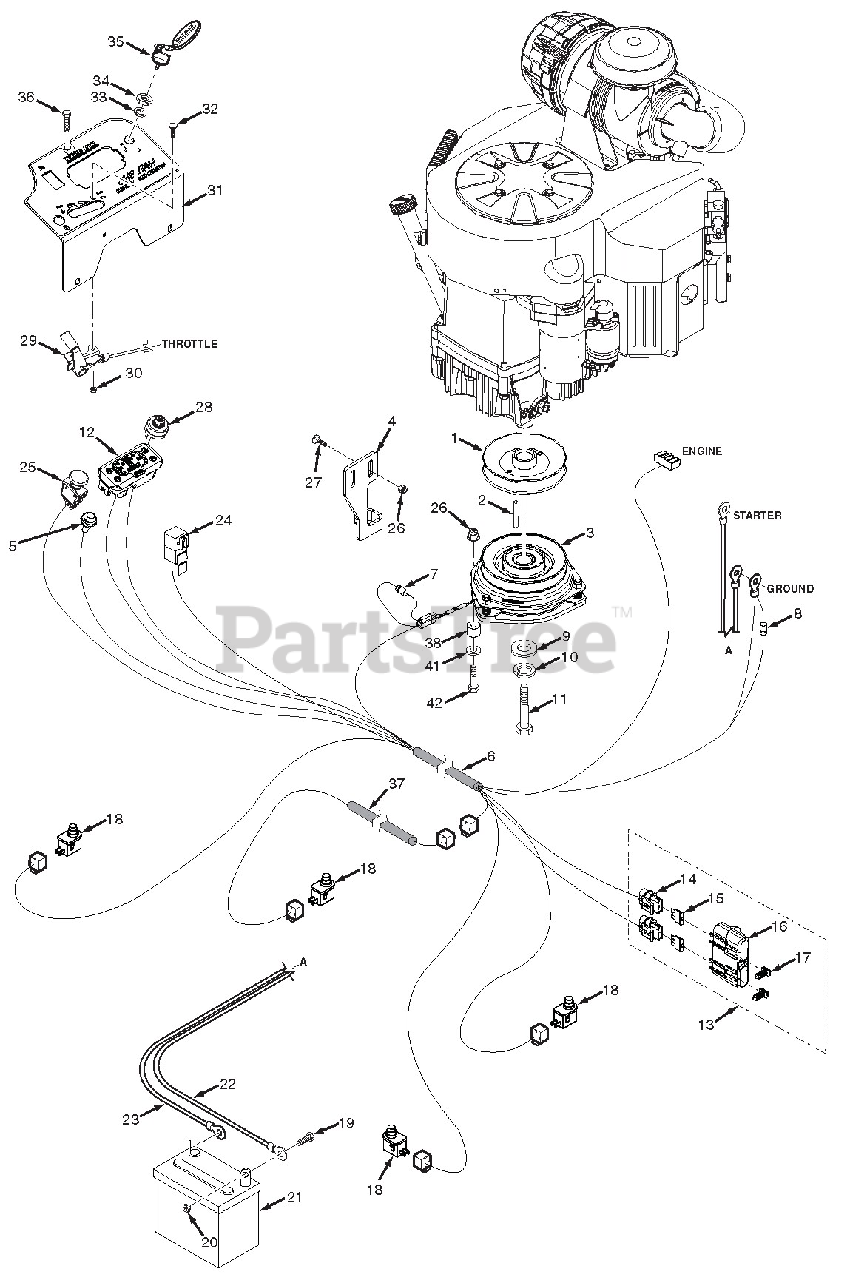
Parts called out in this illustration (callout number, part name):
1	Pulley, 5.80 Dia. - 1.125 Bore
2	Key, 1/4 x 1/4 x 3-1/4"
3	Electric Clutch w/Tag - GT-5 (ECV860, ECV940)
4	Bracket, Anti-Rotation
5	Indicator Light Assembly
6	Wire Harness, SCZ-EFI
7	Diode, 600V - 6A
8	Diode
9	Flatwasher, 7/16-.469 x 1.75 x .25
10	Lockwasher, 7/16" Spring
11	Bolt, Hex Head 7/16-20 x 2-1/4" w/Patch
12	Tiger Eye Cluster Gauge
13	Double Fuse Assembly
14	Fuse Holder
15	Fuse, 20 Amp
16	Cover, Sealed Double
17	Clip, Wire
18	Switch, N.O.
19	Bolt, Hex Head 1/4-20 x 1/2"
20	Nut, 1/4-20
21	Battery
22	Battery Cable, 18" Black
23	Battery Cable, 25" Red
24	Relay
25	Switch, PTO - 10 Amp
26	Nut, FLF HH Elastic Stop 5/16-18
27	Bolt, Carriage 5/16-18 x 1"
28	Keyswitch w/Hardware
29	Control Cable
30	Nut, Elastic Stop #10-24
31	Instrument Panel w/Decal
32	Bolt, Carriage #10-24 x 1/2"
33	Lockwasher, 5/8" Internal
34	Nut, Hex 5/8-32
35	Key Assembly w/Fob
36	Bolt, Hex Head 1/4-20 x 1/2" Serrated Flange
37	Wire Harness, Operator Platform -SCZ
38	Bushing, UHMW
39	Nut, FLF HH Elastic Stop 5/16-18
40	Bolt, Carriage 5/16-18 x 1"
41	Flatwasher, 5/16-.375 x .875 x .083
42	Bolt, Hex Head 5/16-18 x 1-1/2"
